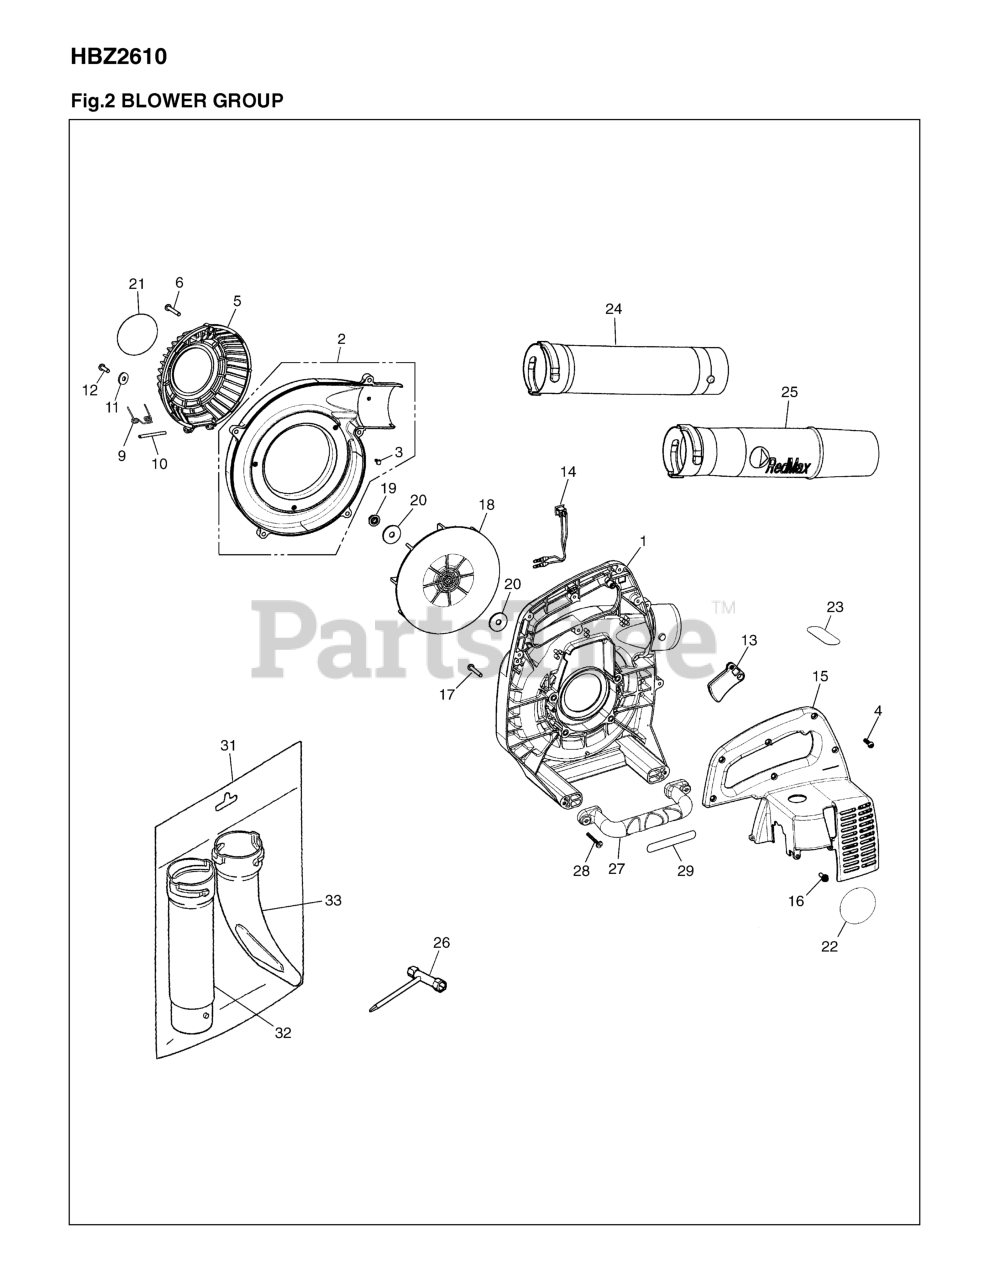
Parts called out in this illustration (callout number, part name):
1	VOLUTE CASE
2	VOLUTE COVER (HBZ2600)
3	SCREW
4	SCREW TORX
5	GUARD NET
6	SCREW, M4x25 (RPLS.0260-30425)
9	SPRING
10	SHAFT
13	LEVER
14	SWITCH
15	ENGINE COVER
16	BOLT
17	SCREW
18	FAN
19	NUT
20	WASHER
21	LABEL, NAME
22	LABEL, RECOIL
23	LABEL CE CAUTION
24	PIPE, STRAIGHT
25	PIPE, END
27	HANDLE
28	SCREW
31	FLAT NOZZLE SET
32	PIPE, STRAIGHT
33	FLAT NOZZLE
